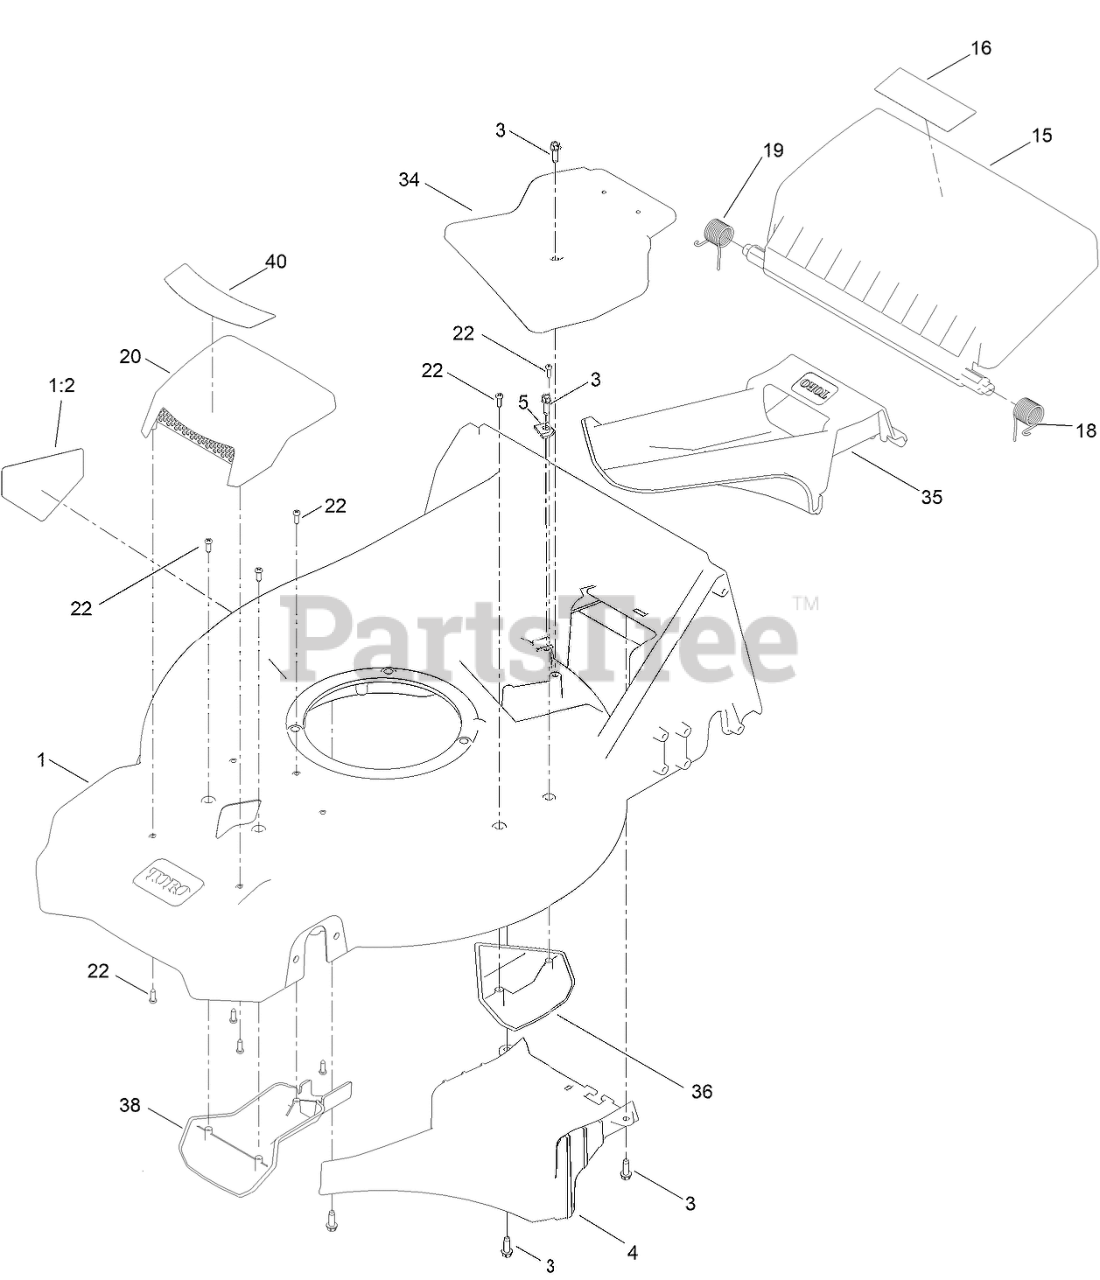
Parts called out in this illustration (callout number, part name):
1	HOUSING ASM
1:2	DECAL-DANGER
3	SCREW-HWHTF
4	RAMP-DISCHARGE
5	CLAMP-CABLE
15	DOOR-REAR
16	DECAL-WARNING
18	SPRING-TORSION, LH
19	SPRING-TORSION, RH
20	ASM-COVER, TOP INTAKE
22	SCREW-PLASTIC, PPH
34	COVER-BELT, TOP
35	PLUG-MULCH
36	KICKER-HOUSING
38	COVER-INTAKE, BOTTOM
40	DECAL-COVER, INTAKE
